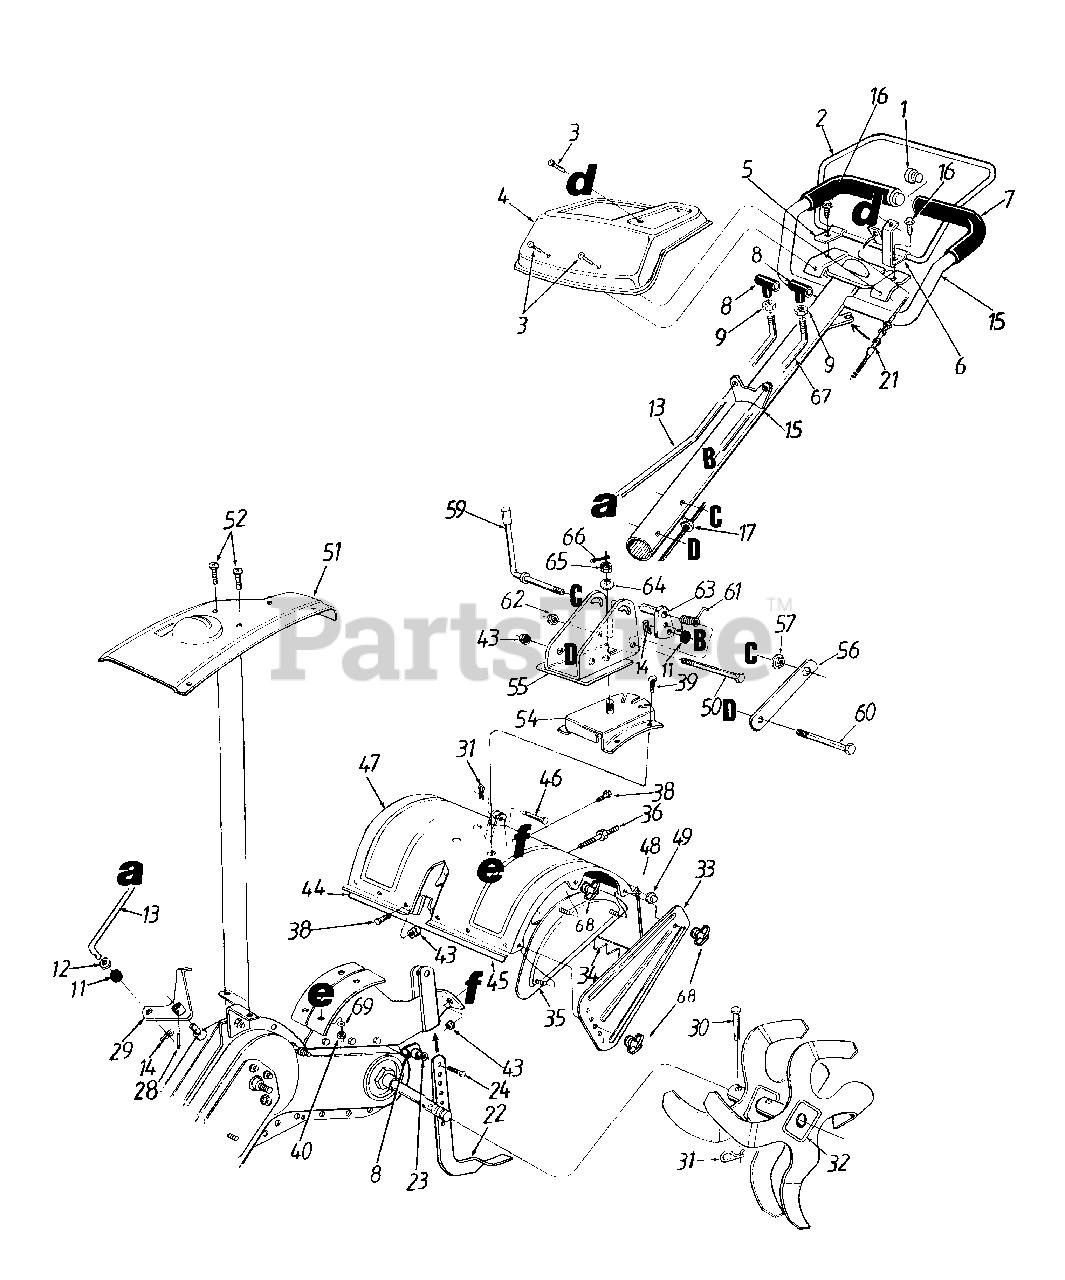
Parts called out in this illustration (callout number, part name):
1	Vinyl End Plug
3	Torx Mach. AB-Tap Scr. 1/4 x .62" Lg.
7	Grip
9	Hex Jam Nut 3/8-16 Thd.
11	Rubber Washer
12	Fl-Wash. .344" I.D. x .6" O.D.
13	Gear Shift Rod
14	Hairpin Clip
15	Handle Ass'y.
16	Tap Scr. 1/4-14 x 5/8" Lg.
17	Cable Clip
21	Clutch Cable
23	Fl-Wash. 3/8" I.D. x 5/8" O.D.
24	Hex Bolt 3/8-16 x 1" Lg.
28	Spiral Pin 3/16" x 1"
31	Hairpin Clip
36	Hex Screw 5/16-18 x .75" Lg.
38	Hex Bolt 5/16-18 x .75" Lg.
39	Carriage Bolt 3/8-16 x 1" Lg.
40	Hex Nut 3/8-16 Thd.
43	Hex Flange Top L-Nut 5/16-18 Thd.
49	Cap Speed Nut
50	Hex Bolt 3/8-16 x 3" Lg.
52	Torx Mach. AB-Tap Scr. 1/4 x .6"
57	Hex Flange Nut 3/8-24 Thd.
59	Handle Adjustment Crank
60	Hex Bolt 5/16-18 x 3" Lg.
61	Torsion Spring
62	Hex L-Nut 3/8-16 Thd.
63	Handle Swing Link
64	Bell-Wash. 5/8" I.D.
65	Hex Slotted Nut 5/8-18 Thd.
66	Cotter Pin 1/8" x 1-5/8"
67	Handle Adjustment Rod
68	Knob 5/16-18 Thd.
69	L-Washer 3/8" I.D.
